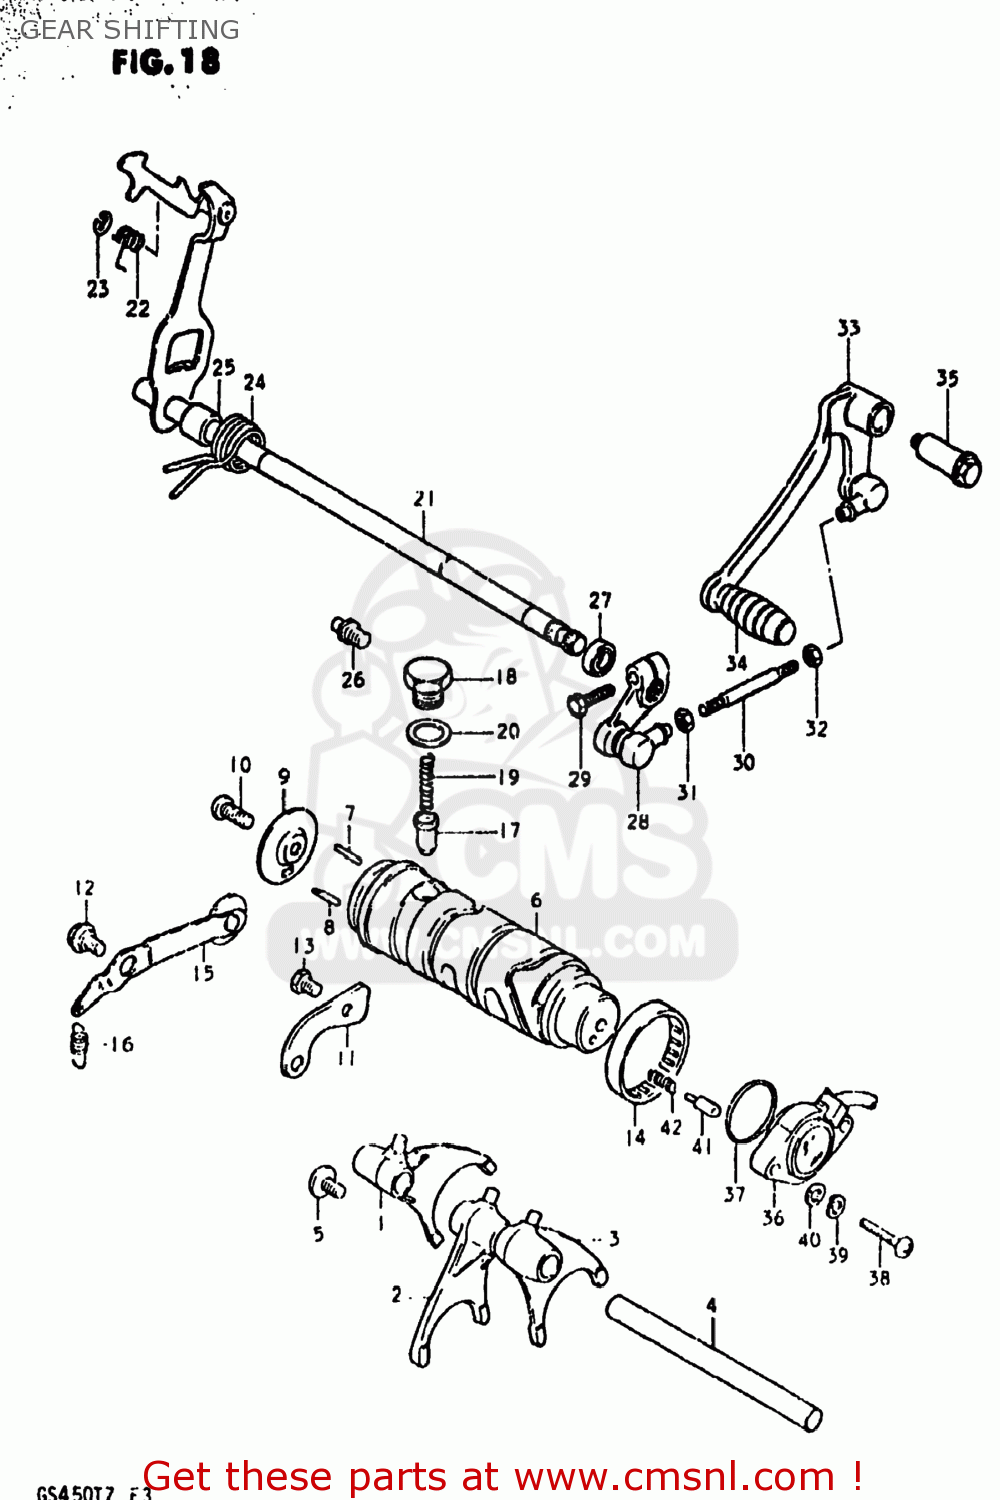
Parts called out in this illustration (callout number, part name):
1	FORK,GEAR SHIFT NO.1
2	FORK,GEAR SHIFT NO.2
3	FORK,GEAR SHIFT NO.2
4	SHAFT,GEAR SHIFT FORK
5	SCREW
6	CAM,GEAR SHIFT
7	PIN(4X18.5)
8	PIN
9	RETAINER,GEAR SHIFT CAM DR PIN
10	SCREW
11	GUIDE,GEAR SHIFTING CABLE
12	BOLT
13	BOLT, UPPER
14	BEARING(40X47X12)
15	STOPPER,GEAR SHIFT CAM NO.1
16	SPRING
17	STOPPER,GEAR SHIFT CAM NO.2
18	HOLDER,GEAR SHIFT CAM STOP SPR
19	SPRING
20	GASKET(14X19.2X2) (NAS)
21	SHAFT,GEAR SHIFT
22	SPRING
23	E RING
24	SPRING
25	SPACER(12X20X15.3)
26	STOPPER,GEAR SHIFT CAM
27	OIL SEAL
28	ARM,GEAR SHIFT LINK
29	BOLT
30	ROD,GEAR SHIFT LINK
31	NUT
32	NUT
33	LEVER ASSY,GEAR SHIFT
34	RUBBER,GEAR SHIFT PEDAL
35	SHAFT,GEAR SHIFT LEVER
36	TERMINAL BASE ASSY,GEAR SHIFT
37	O-RING (D:2.4 ID:26.2)
38	SCREW 5X20
39	LOCK WASHER
40	WASHER
41	PIN(5X15.5)
42	SPRING
